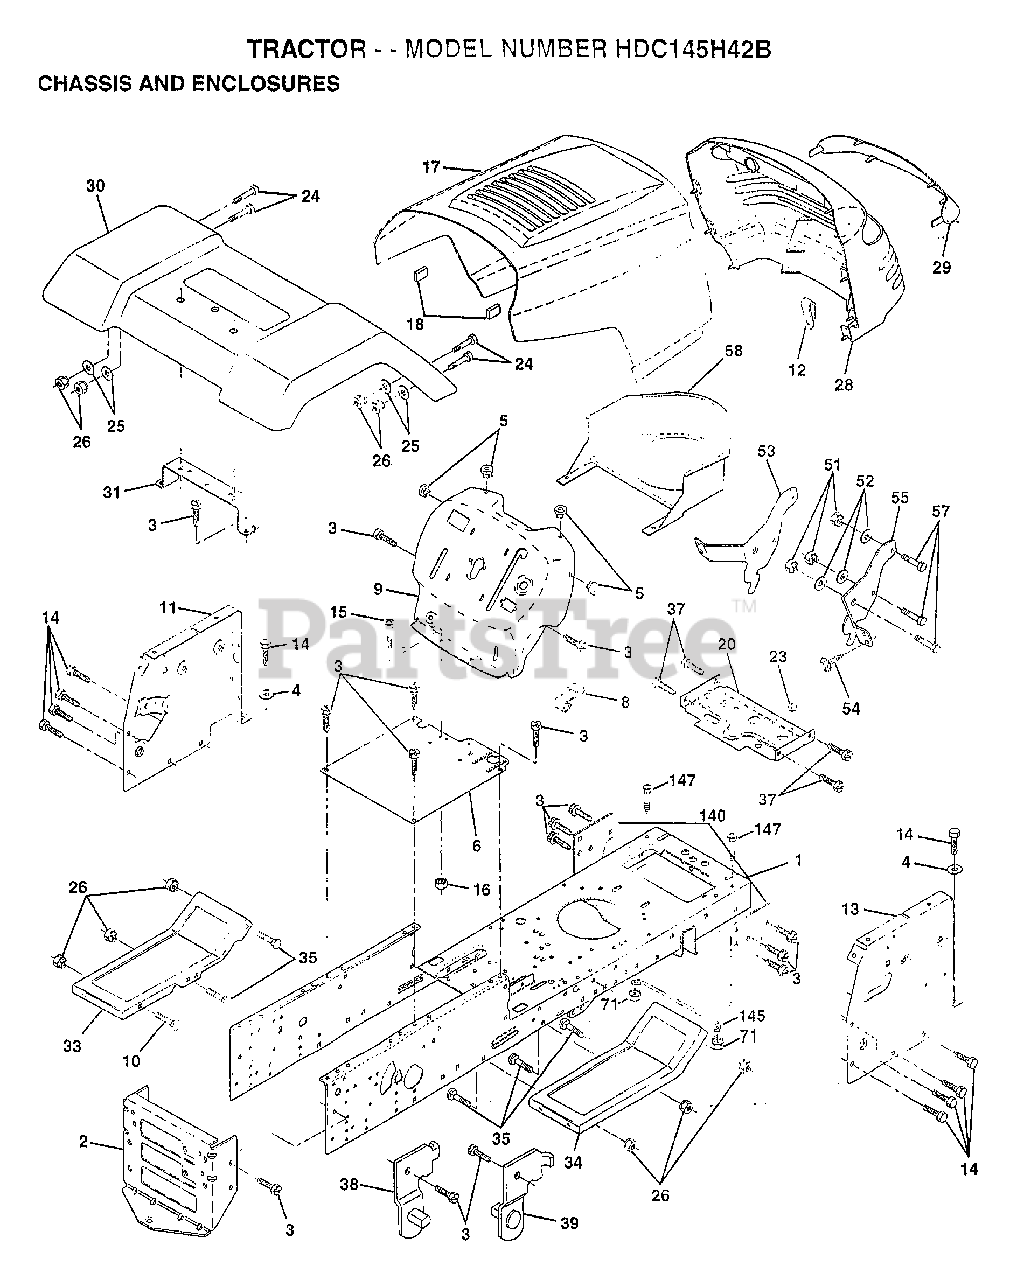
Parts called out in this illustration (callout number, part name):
1	CHASSIS ASM
3	SCREW
4	WASHER
5	BUMPER-HOOD/DASH
6	SADDLE
8	CLIP.RETAINER
9	DASH.SILKSCREENED
11	"PANEL-DASH,LH"
12	CLIP.TINNERMAN
14	SCREW LT
15	SCREW
20	"PLATE-MTG,BATT/FU"
24	BOLT
25	WASHER
26	NUT
28	GRILLE-MS428
29	LENS GRILLE
30	FENDER ASM LT W/S
31	BRKT FENDER
33	FOOTREST LH
34	FOOTREST RH
35	BOLT
37	SCREW LT
38	BRACKET ASM LH
39	BRACKET ASM RH
51	NUT
52	WASHER
53	BRACKET.GRILLE.LH
55	BRACKET.GRILLE.RH
58	AIR DUCT
140	BRKT SUSPENSION
145	"ROD POVOT,CHASSIS"
147	BOLT LT
